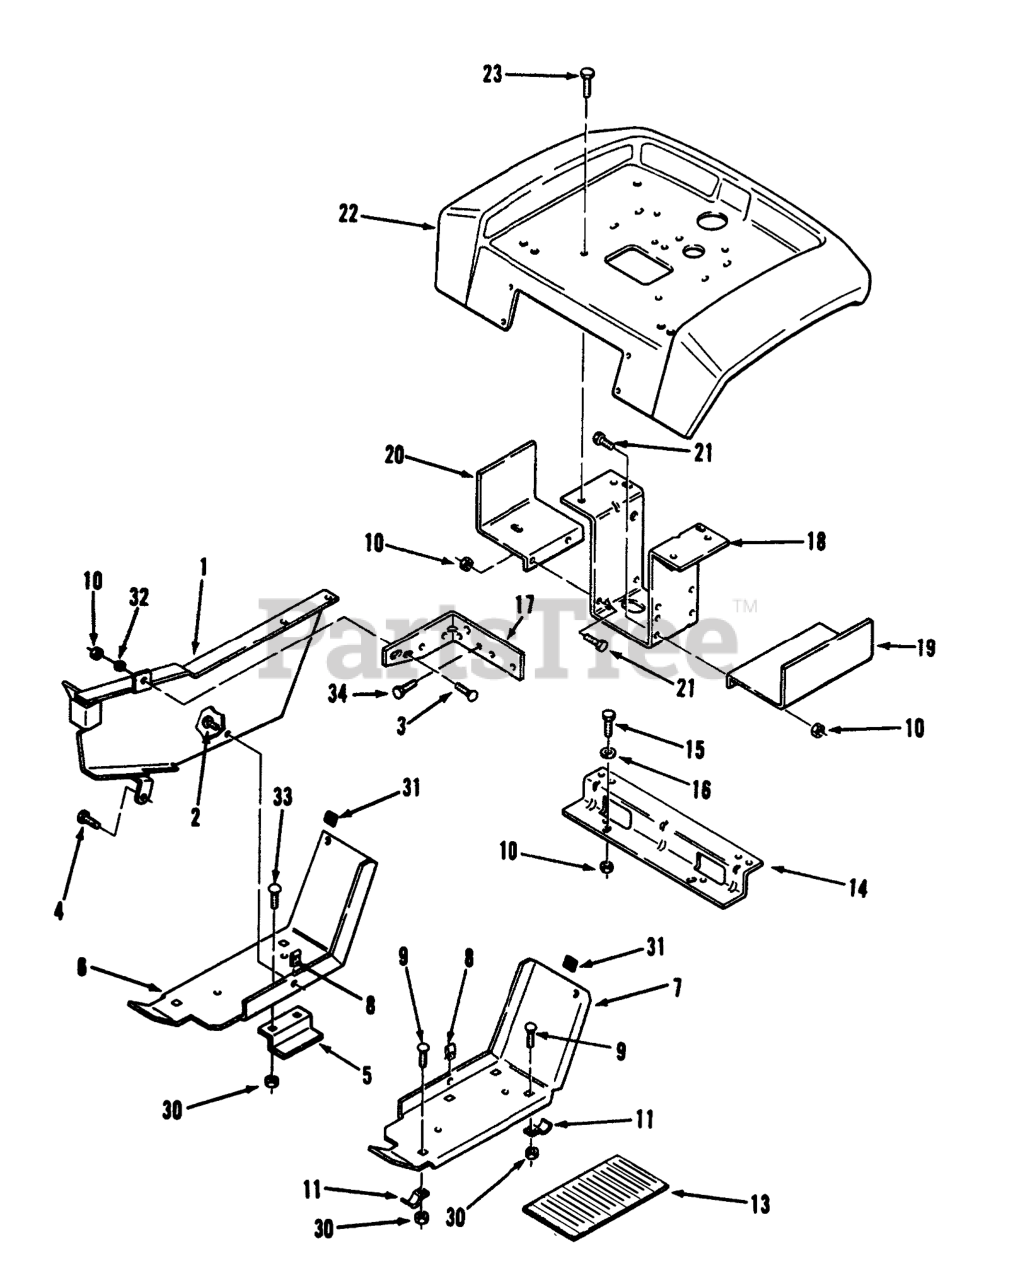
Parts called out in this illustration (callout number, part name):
1	Belt Guard
2	Screw
3	BOLT-CARR
4	SCREW
5	GUID-LOWER BLTR
6	RH FOOTREST MAT
7	RH FOOTREST MAT
9	BOLT-CARR
10	NUT-LOCK, NI
11	BRACKET
13	PAD FOOTREST
14	BRACKET-FENDER B
15	SCREW-HH
16	WASHER-PLAIN
17	BRACKET-BELTB
18	Bracket-Fender
19	Fuel Tank Support LH
20	Support-FueITank RH
21	SCREW-HH
22	Fender
23	SCREW
30	NUT-LOCK, NI
31	BUMPER
32	NUT-PUSH
33	BOLT-CARR
